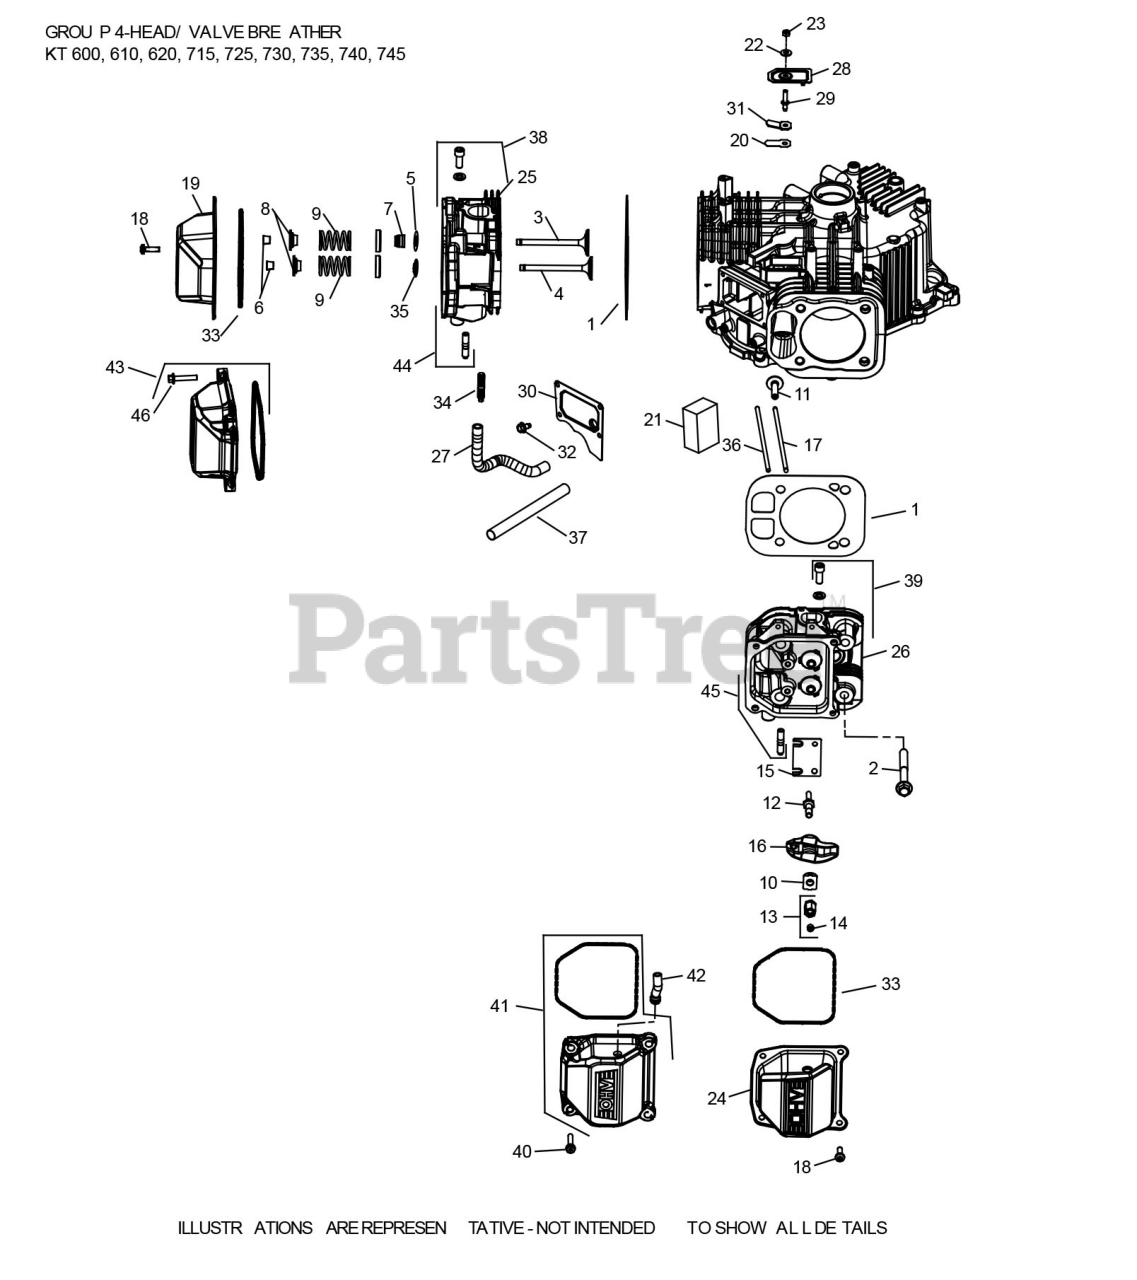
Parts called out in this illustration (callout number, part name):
1	GASKET KIT-CYL HEA
3	INTAKE VALVE .25
4	EXHAUST VALVE
4	EXHAUST VALVE .25
6	KIT-RETAINER
7	VALVE STEM SEAL
8	VALVE CAP SPRING
10	PIVOT- ROCKER ARM
11	TAPPET-PUSH ROD
13	NUT ASSEMBLY-ROCKER
20	BREATHER REED
21	BREATHER FILTER
22	SEALING WASHER
27	BREATHER HOSE
28	COVER-BREATHER REED
29	STUD-BRETHR REED C
30	COVER-BREATHER FILTE
31	RETAINER-BREATHER
33	O-RING VLV CVR
35	VALVE GUIDE RETAINER
41	KIT-ROCKER COVER
42	HOSE KIT-FUEL PUMP
43	COVER KIT-ROCKER
